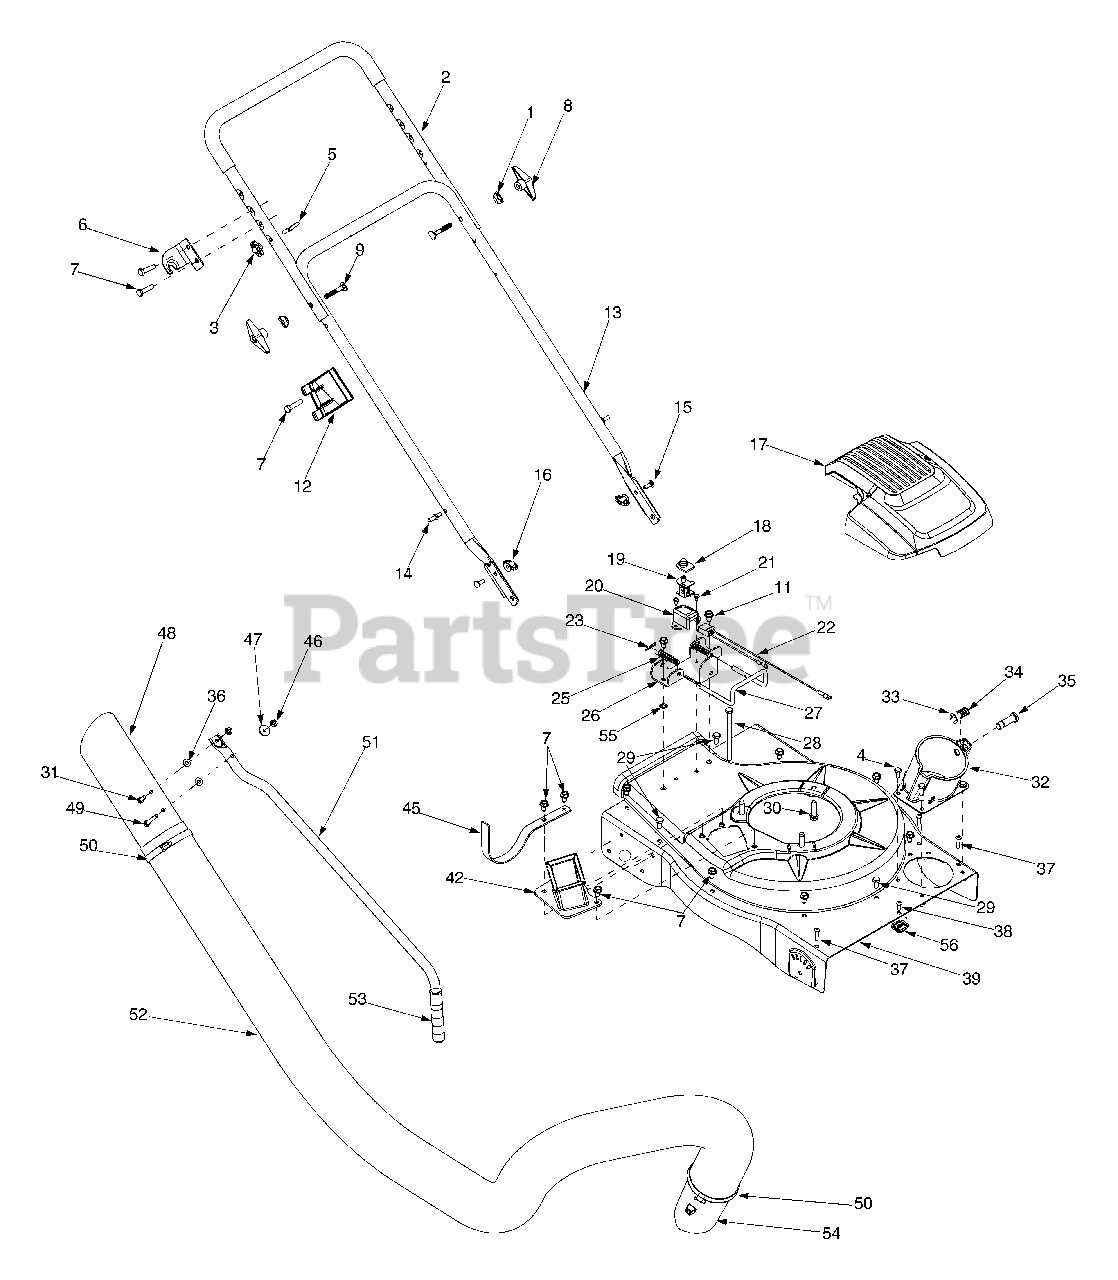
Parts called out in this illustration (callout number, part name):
1	Saddle Washer,.320 x.93
4	Screw, 1/4-20 x.500
5	Eye Bolt
7	Hex Cap Screw 5/16-12 x.750
8	Handle Knob 5/16-18
9	Carriage Bolt
12	Nozzle Handle Clip
14	Studs
15	Carriage Screw 1/4-20 x.75
16	Wing Nut 1/4-20
18	Switch Cover
19	Safety Switch
20	Safety Switch Cover
21	Hex Washer Screw #10-16 x.50
22	Wire Harness
23	Cotter Pin
25	Compression Spring
27	Lock Rod
28	Hex Cap Screw 5/16-18 x 4.5
29	Hex Cap Screw 5/16-18 x.625
30	Hex Washer Screw 3/8-16 x 1.25
31	Hex Cap Screw 1/4-20 x.620
32	Hose Base Adapter
33	E Ring.500 Dia
34	Compression Spring
35	Clevis Pin
36	Flat Washer.271 ID x.630 OD
37	Screw, #12-16 x.750
38	Screw #10 - 16 x.500
47	Spacer
48	Hose Nozzle
49	Hex Cap Screw 1/4-20 x 2.625
50	Adjustment Clamp
52	Vacuum Hose
53	Handle Grip
54	Hose Adapter
55	External L-Washer 5/16
56	Speed Nut
